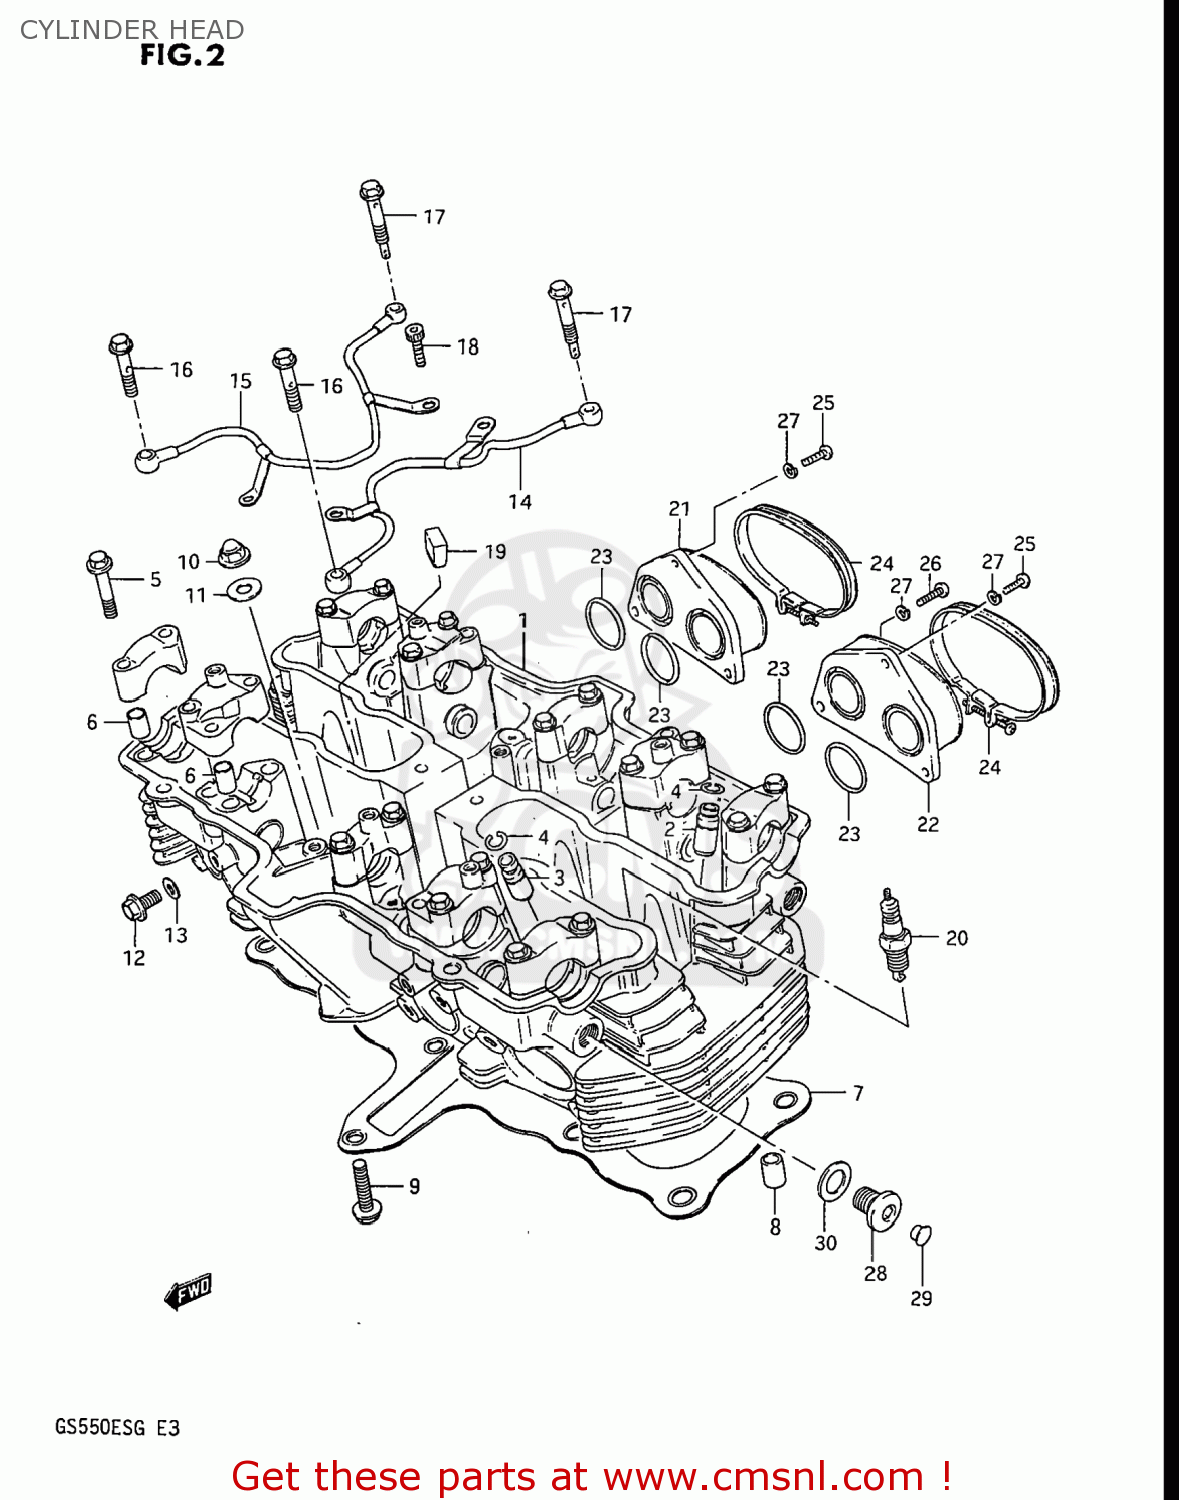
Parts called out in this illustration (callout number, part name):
1	HEAD ASSEMBLY,CYLINDER
2	GUIDE,VALVE
3	GUIDE,VALVE
4	RING,SNAP
5	BOLT(6X39)
6	PIN(6.2X8X11)
7	GASKET,CYLINDER HEAD (NAS)
8	PIN
9	BOLT
10	NUT
11	GASKET(8.5X20X2.3) (NAS)
12	BOLT
13	GASKET(6.2X13X1.2) (NAS)
14	PIPE,OIL CYLINDER HEAD
15	PIPE,OIL CYLINDER HEAD
16	UNION
17	BOLT,UNION
18	BOLT, 6X16
19	PAD,CYLINDER
20	SPARK PLUG D9EA
21	PIPE,INTAKE,R
22	PIPE,INTAKE,L
23	O-RING (D:2.4 ID:29.7)
24	CLAMP
25	SCREW
26	SCREW
27	WASHER,LOCK
28	PLUG
29	CAP(OD:12)
30	GASKET(14X19.2X2) (NAS)
